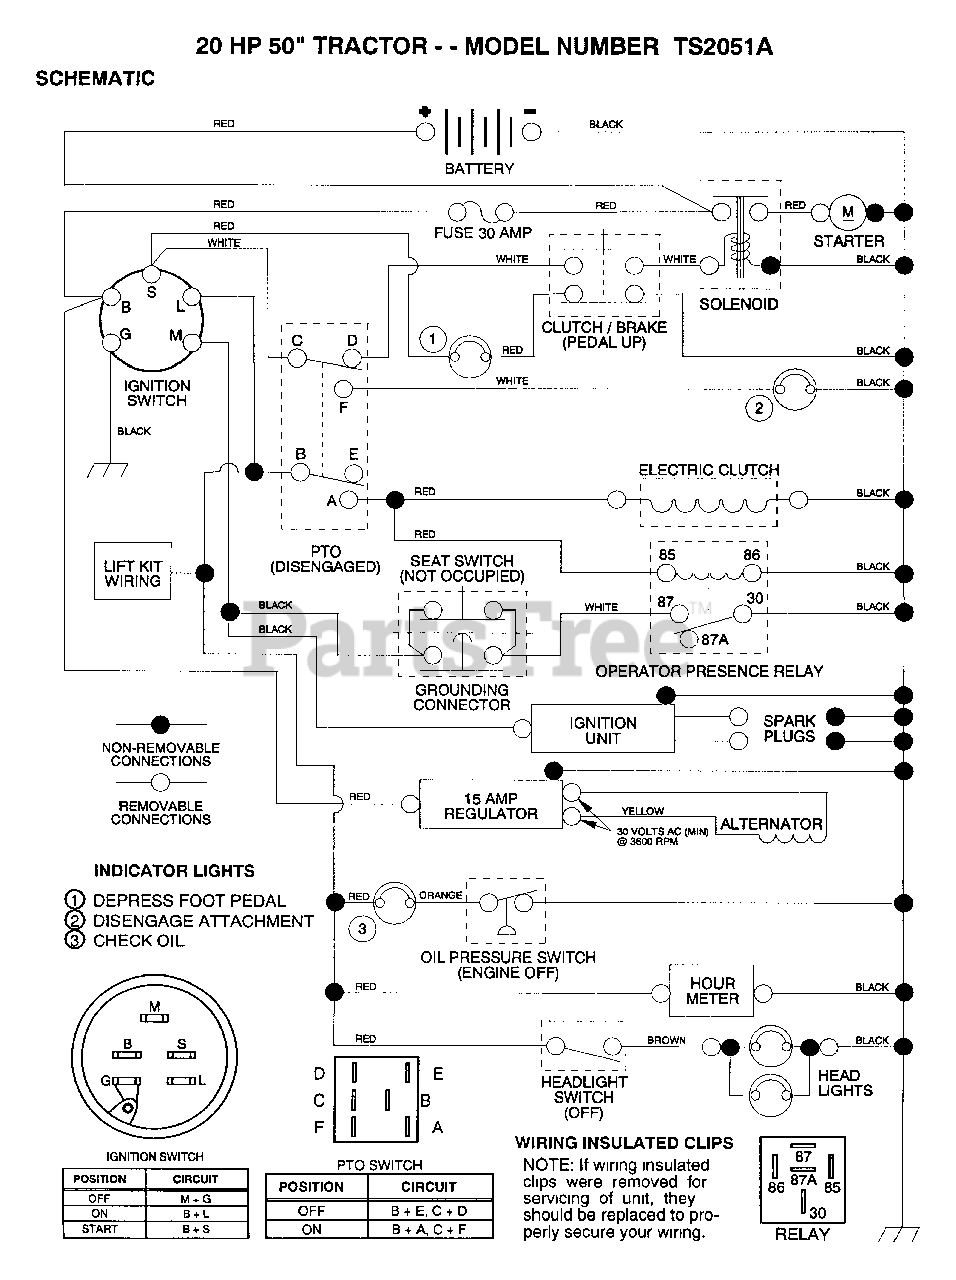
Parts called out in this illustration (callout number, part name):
5	DECAL
7	DECAL WARING
8	DECAL.STRG.WHL
11	PLATE.NAME.SMALL
12	DECAL.PANEL.SIDE
